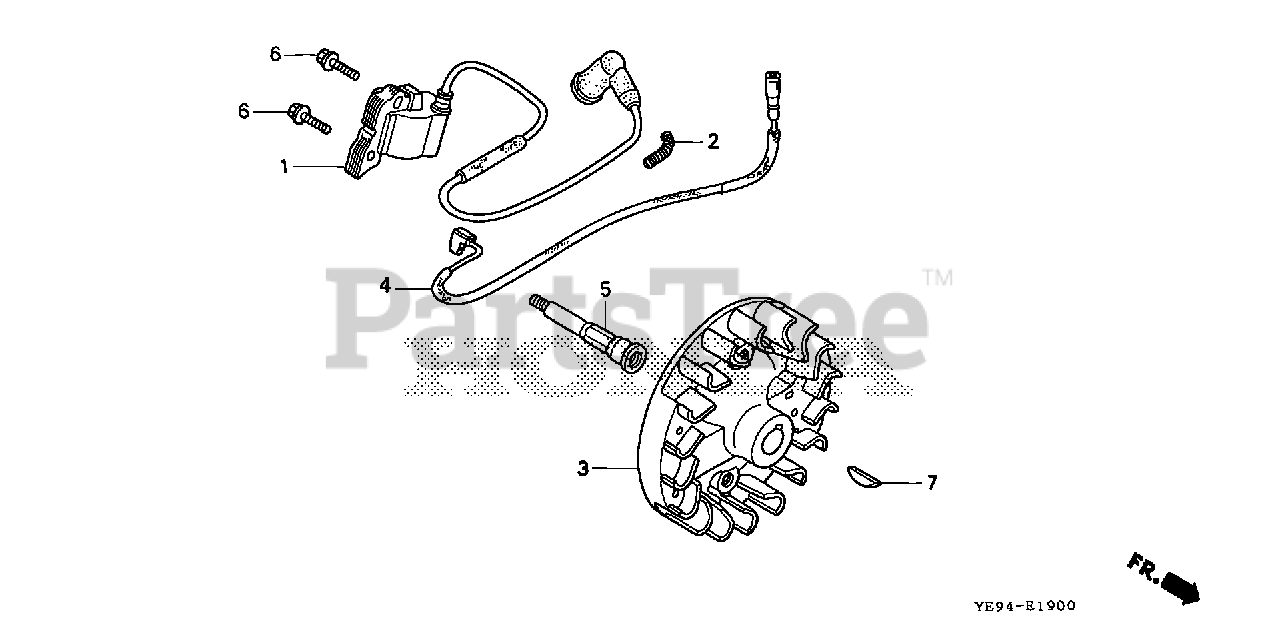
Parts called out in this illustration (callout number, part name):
1	COIL ASSY., IGNITION
2	TUBE A, CORRUGATED (7X18)
4	WIRE, STOP SWITCH
5	SHAFT, P.T.O.
6	BOLT-WASHER (5X16)
7	KEY, WOODRUFF (16X12)
